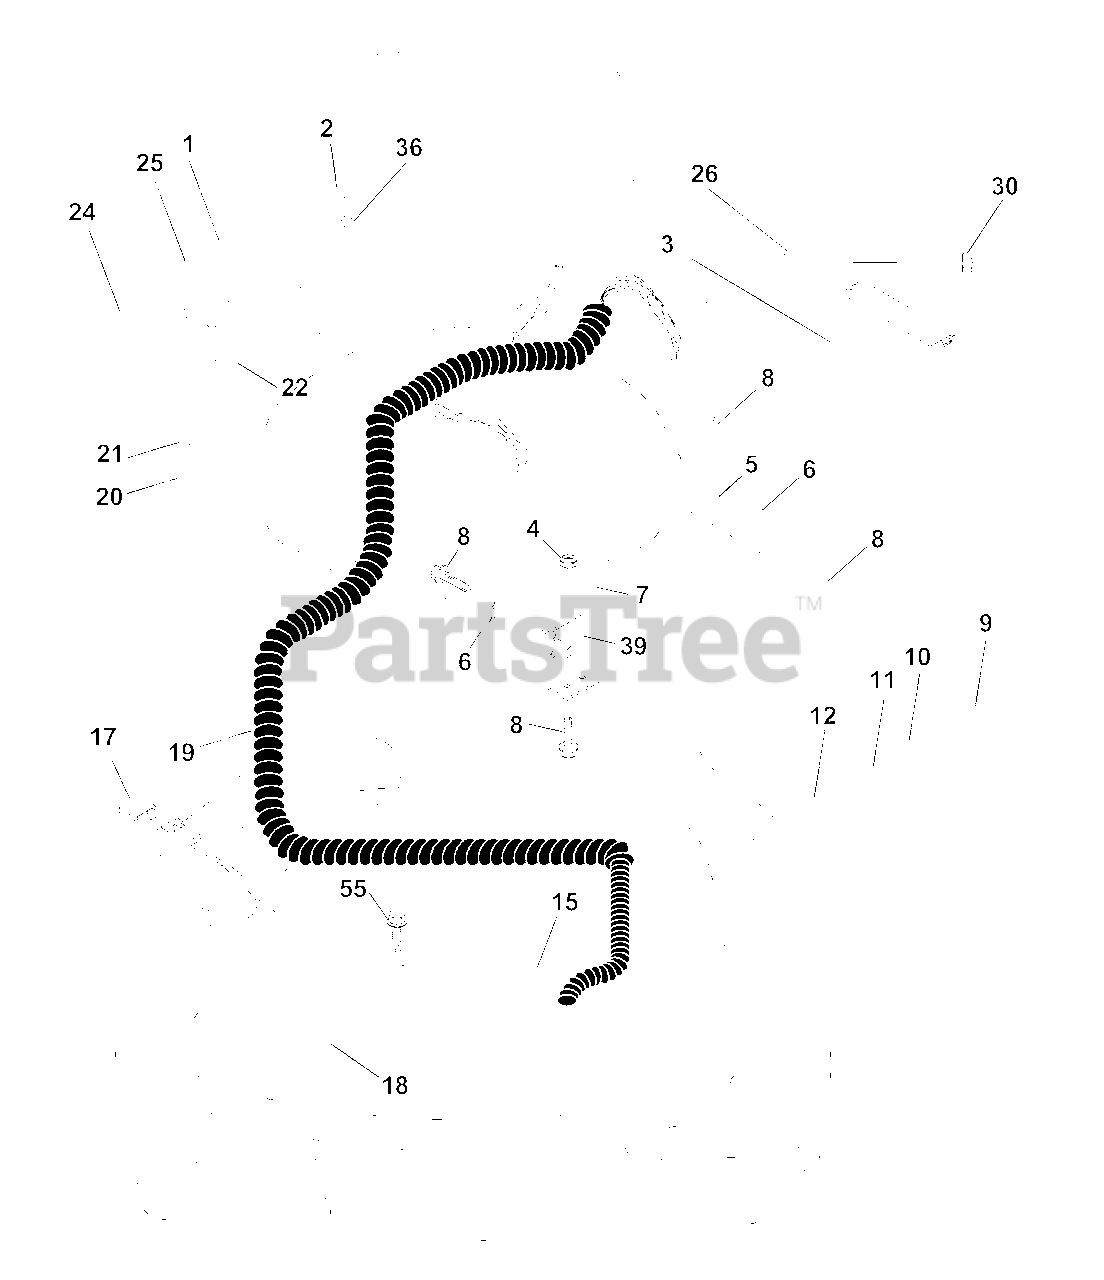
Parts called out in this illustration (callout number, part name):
1	Nut, Hex Keps 1/4-20
2	Assembly, Cable
3	Battery
4	Nut, Lock #10-24 UNC
5	Bracket, Switch
6	Switch, Interlock (4-terminal)
7	Keeper Actuator
8	Screw, Hex Hd. Tap #10-24 x 1/2
9	Key, Steel Delta
10	Cover, Key Ignition
11	Nut, Ignition
12	Switch, Ignition
15	Switch, Plunger
17	Fuse
18	Assembly, Cable
19	Harness, Ignition
20	Nut, Hex Jam 1/4-20
21	Washer, Lock 1/4
22	Bolt, Fin. Hex 1/4-20 UNC x 1/2 Gr. 5
24	Cover, Terminal
25	Solenoid
26	Bolt, Hex Hd. 1/4-20 UNC x 3/4
30	Nut, Keps Hex 1/4-20 UNC
36	Washer, Lock Inter. Tooth 1/4
39	Bracket, Switch Clutch
55	Screw Thdrol 5/16-18 x 1/2
